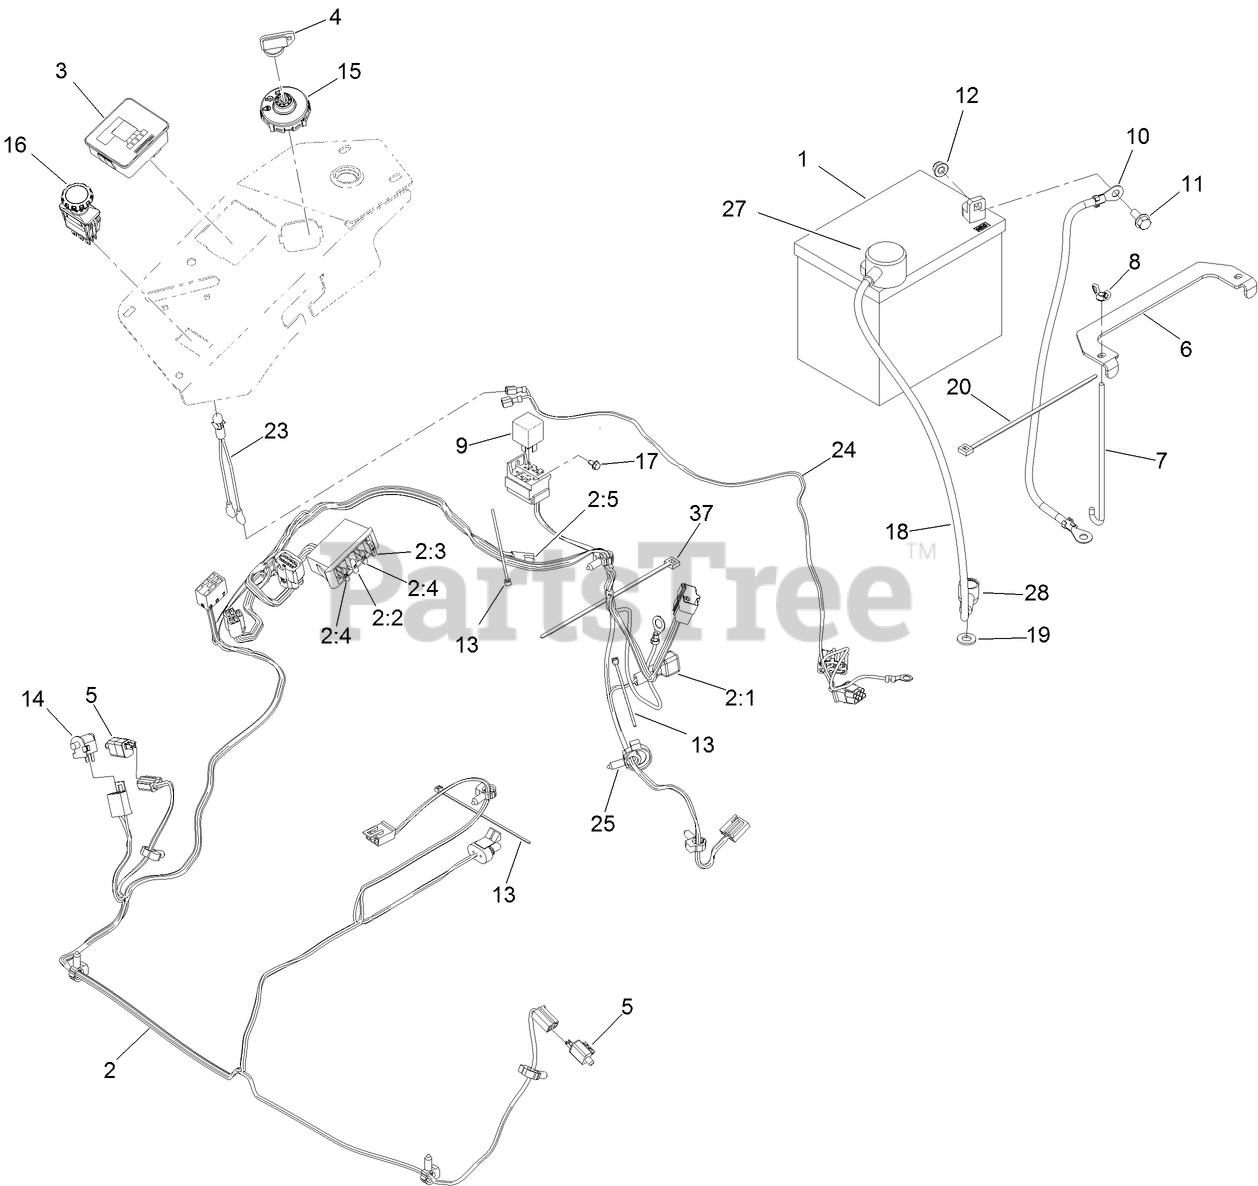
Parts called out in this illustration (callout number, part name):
1	BATTERY-DRY
2	HARNESS-WIRE, MAIN
2:2	FUSE-BLADE, 10 AMP
2:3	FUSE-BLADE, 15 AMP
2:4	FUSE-BLADE, 25 AMP
2:5	CAP-PLUG
3	FUEL/HOUR METER ASM
4	KEY-IGNITION
5	SWITCH
6	STRAP-TIE DOWN, BATTERY
7	BOLT-HOLDDOWN
8	WINGNUT
10	CABLE-BATTERY, NEGATIVE
11	SCREW-HHF
12	NUT-HF, NI
13	TIE-CABLE
14	SWITCH-BAIL
15	SWITCH-IGNITION
16	SWITCH-PTO, 10 AMP
17	SCREW-HWH
18	CABLE-BATTERY, POSITIVE
19	WASHER-FLAT
20	TIE-PLASTIC
23	INDICATOR-LED, RED
24	HARNESS-LIGHT, INDICATOR
25	CLAMP-HOSE
27	INSULATOR-BATTERY
28	INSULATOR-SOLENOID
37	TIE-PLASTIC
